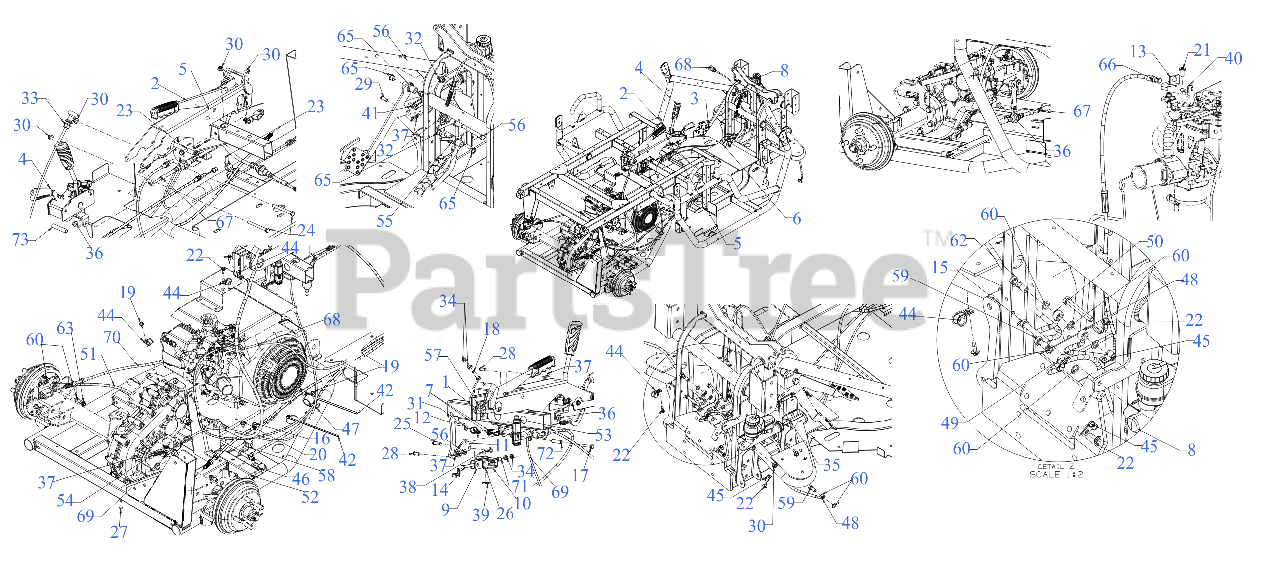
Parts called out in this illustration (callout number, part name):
1	PLATE-SWITCH
2	LEVER ASSEMBLY:BRAKE
4	COMPLETE SHIFT DIFF ASSEMBLY
5	PARKING BRAKE CONTROL MOUNT BRACKET
8	MASTER CYLINDER ASSEMBLY
9	CABLE MOUNTING BRACKET
10	EQUAIZER BRACKET
11	BRAKE LEVER BRACKET
12	BRAKE LINK BRACKET
13	THROTTLE CABLE MOUNTING BRACKET
14	SCREW 5/16-18 x 2.5 GR 5
15	HEX SCREW 5/16-18 x 2.25 GR5
16	SCREW 5/16-18 x .750
17	SCREW 1/4-20 x 2 GR5
18	SCREW 5/16-18 x 1.25 GR5
19	SCREW 1/4-20 X.500
20	SCREW 5/16-18 x .500
21	SCREW M5-.8X10MM SLOT/TORX
22	SCREW M6-1 x .625
23	SCREW 5/16-18 x .875 GR5
24	SCREW 5/16-18 x 3.25 GR5
25	CLEVIS PIN .375 DIA x .969
26	BRAKE CABLE PIN
27	CLEVIS PIN .25 x 1.00
28	CLEVIS PIN 5/16 x 3/4
29	CLEVIS PIN .312 x 1.0
30	FLANGE LOCK NUT 5/16-18
31	FLANGE LOCK NUT
35	HEX JAM NUT 5/16-24 GR 5
36	HEX FLANGE NUT M8X
37	BOW TIE COTTER PIN 1/4-5/16
38	PIN:COTTER
40	EXTERNAL RETAINING RING 7MM
41	ADJUSTABLE ROD END
42	7" CABLE TIE
45	MOUNTING CLAMP
46	J TYPE CLIP
47	HOSE CLAMP 1.0"
48	FRONT BRAKE HOSE (RH)
49	MASTER CYLINDER BRAKE HOSE (REAR)
50	FRONT BRAKE HOSE (RH)
51	FRONT BRAKE HOSE (LH)
52	BRAKE HOSE (RH)
53	SEALED PLUNGER SWITCH
54	EXTENSION SPRING .420X1.50
55	GAS PEDAL TORSION SPRING
56	FLAT WASHER .344 x .62
57	FLAT WASHER.344X.75X.1
58	TEE FITTING
59	BANJO FITTING
60	BANJO FITTING
62	BANJO BOLT FITTING
63	BANJO BOLT 3/8-24
64	SHOULDER BOLT .50 x 2.5 x 3/8 -16
65	NYLINER BEARING
66	THROTTLE CONTROL CABLE
67	SHIFT CONTROL CABLE
68	CHOKE CABLE 93"
69	DIFF LOCK CONTROL CABLE
70	PARKING BRAKE CABLE 65"
72	SPACER:.260 x .372 x 1.420
